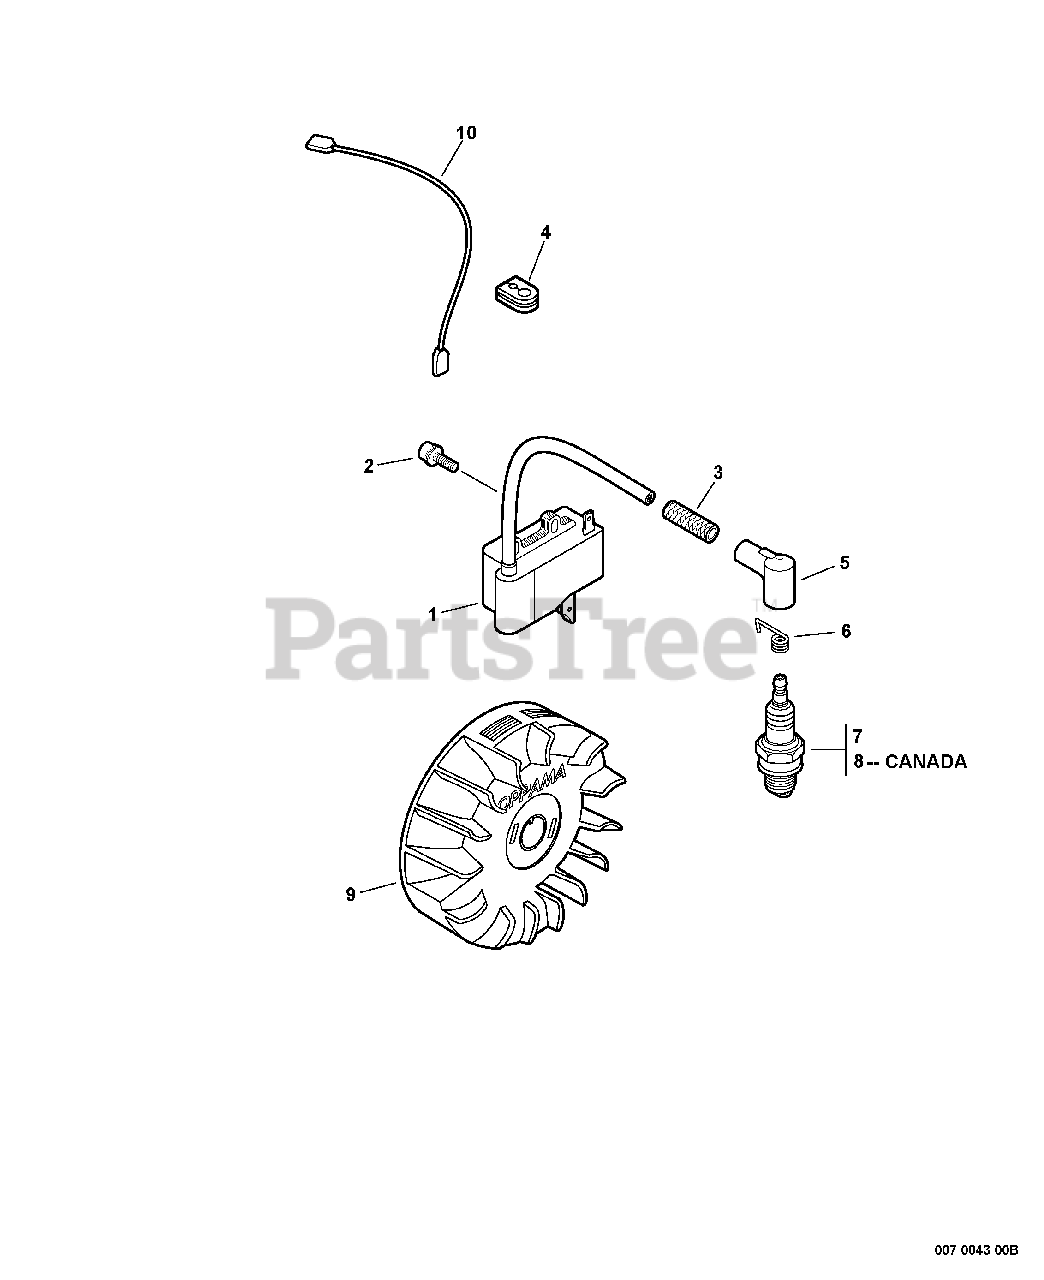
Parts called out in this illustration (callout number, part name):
1	COIL, IGNITION
2	BOLT 4×20
3	TUBE, INSULATOR
5	CAP, SPARK PLUG
6	TERMINAL, SPARK PLUG
7	SPARK PLUG - BPM8Y
8	SPARK PLUG - BPMR8Y
9	FLYWHEEL
10	LEAD
